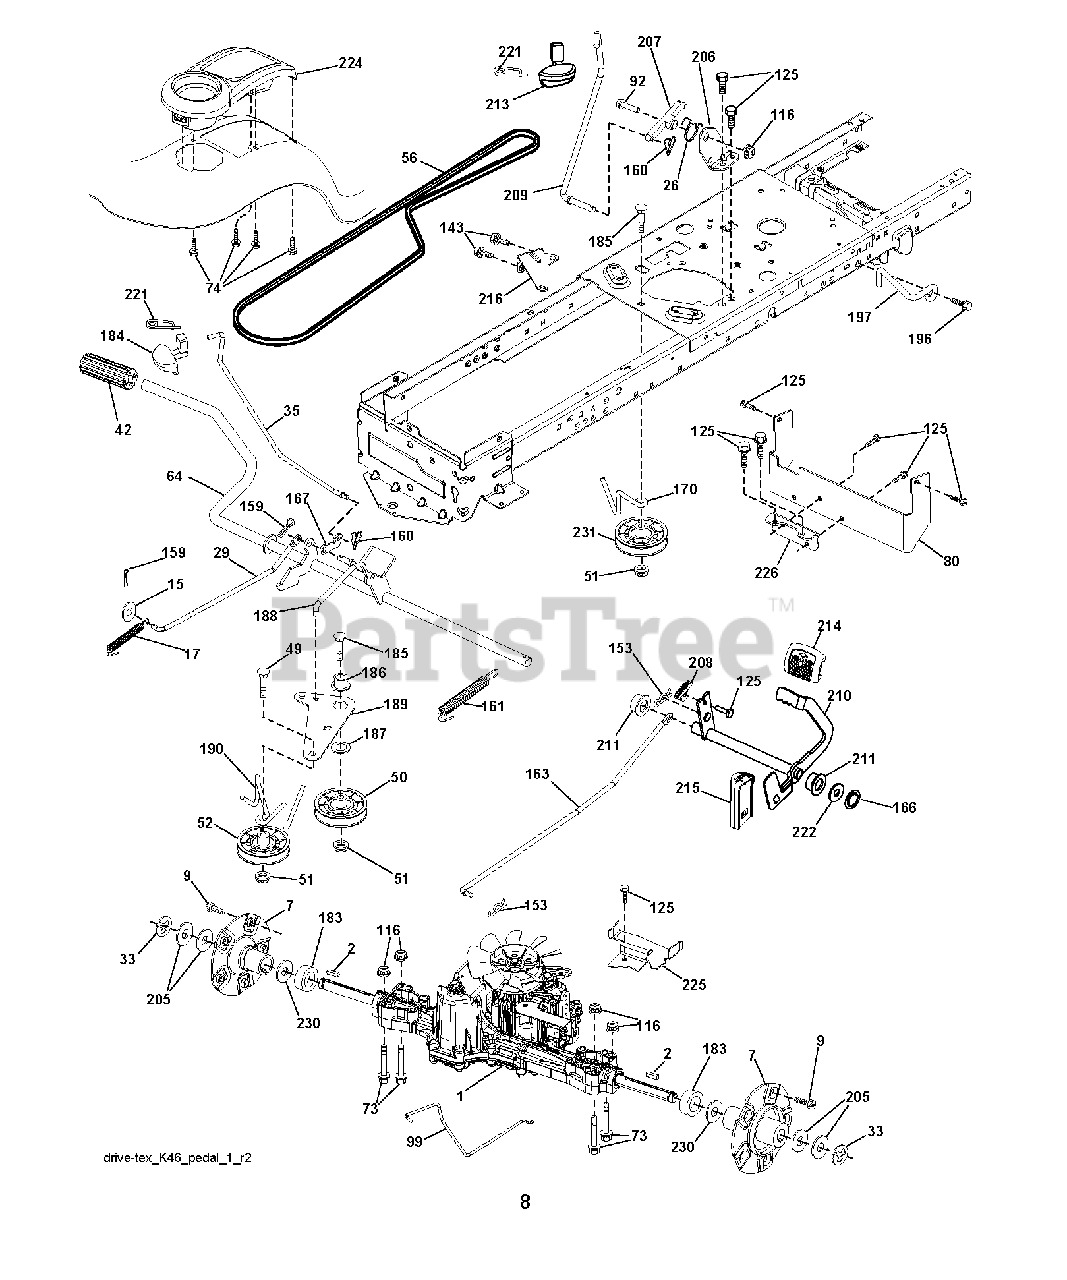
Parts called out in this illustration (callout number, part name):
2	KEY.SQUARE.187X2.500
7	HUB.ASM.WHEEL.REAR.22"
17	SPRING.BRAKE.K46.GREEN
26	SPRING.RETURN.CRUISE
29	ROD.BRAKE.K46
33	E-RING LT
35	ROD.BRAKE.PARKING.GT.H
42	PEDAL COVER T
49	BOLT
50	IDLER.FLAT.910.OFFSET
51	NUT LOCK FLG 3/8-16 UNC
52	IDLER.V-GROOVE.910.OFFSET
64	SHAFT.ASM.PEDAL.BRK.CNTR
73	BOLT HEX 5/16-18 GR 5
74	SCREW.HI-LO.CONSOLE
80	STRAP TORQUE
92	BOLT
99	ROD.SPRING.BYPASS.K46.LT.Z
116	NUT LOCK HEX FLANGE 5/16-18
125	SCREW
153	RETAINER M
159	COTTER PIN
160	RETAINER CLIP
161	SPRING, RETURN LT
163	ROD.CONTROL.PEDAL.K46
166	NUT.PUSH.625
167	LATCH.BRAKE.SPRING
170	KEEPER.CENTER SPAN.1.688
183	SPACER.SPLIT.800X.350
184	HANDLE.PARKG.BRK.HUSQ/
186	SPACER.RETAINER
187	WASHER 12/32X2X10GA
188	LINK.CLUTCH.GROUND.DRIVE
189	BELLCRANK.GROUND.DRIVE.TEX.
190	KEEPER.BELLCRANK.DRIVE
196	SCREW 3/8-16X1
197	BRKT.ANIT-ROTATION.CLU
206	BRKT.MOUNT.LATCH.CRUIS
207	LATCH.CONTROL.CRUISE
208	GEAR.SECTOR.CONTROL.CR
209	ROD.CONTROL.CRUISE.GT.
210	ROCKER.ASM.PEDAL.CONTR
211	BEARING.NYLON
213	KNOB.CONTROL.CRUSIE.HU
214	PAD PEDAL FORWARD
215	PEDAL.REVERSE.TEX.GT.4
216	BRACKET.PULLEY.IDLER.W/TEX
221	RETAINER.SPRING.CLIP.H
222	WASHER 21/32 X 1-1/4 X 10 GA.
224	CONSOLE.TOOLBOX.PCH.ERGO.BLACK
225	KEEPER.BELT.TRANSAXLE.K46
226	BRACKET.MOUNT.TORQUE.K46.TLT
230	WASHER.HARDENED
231	IDLER.V-GROOVE.1.688.OFFSET
